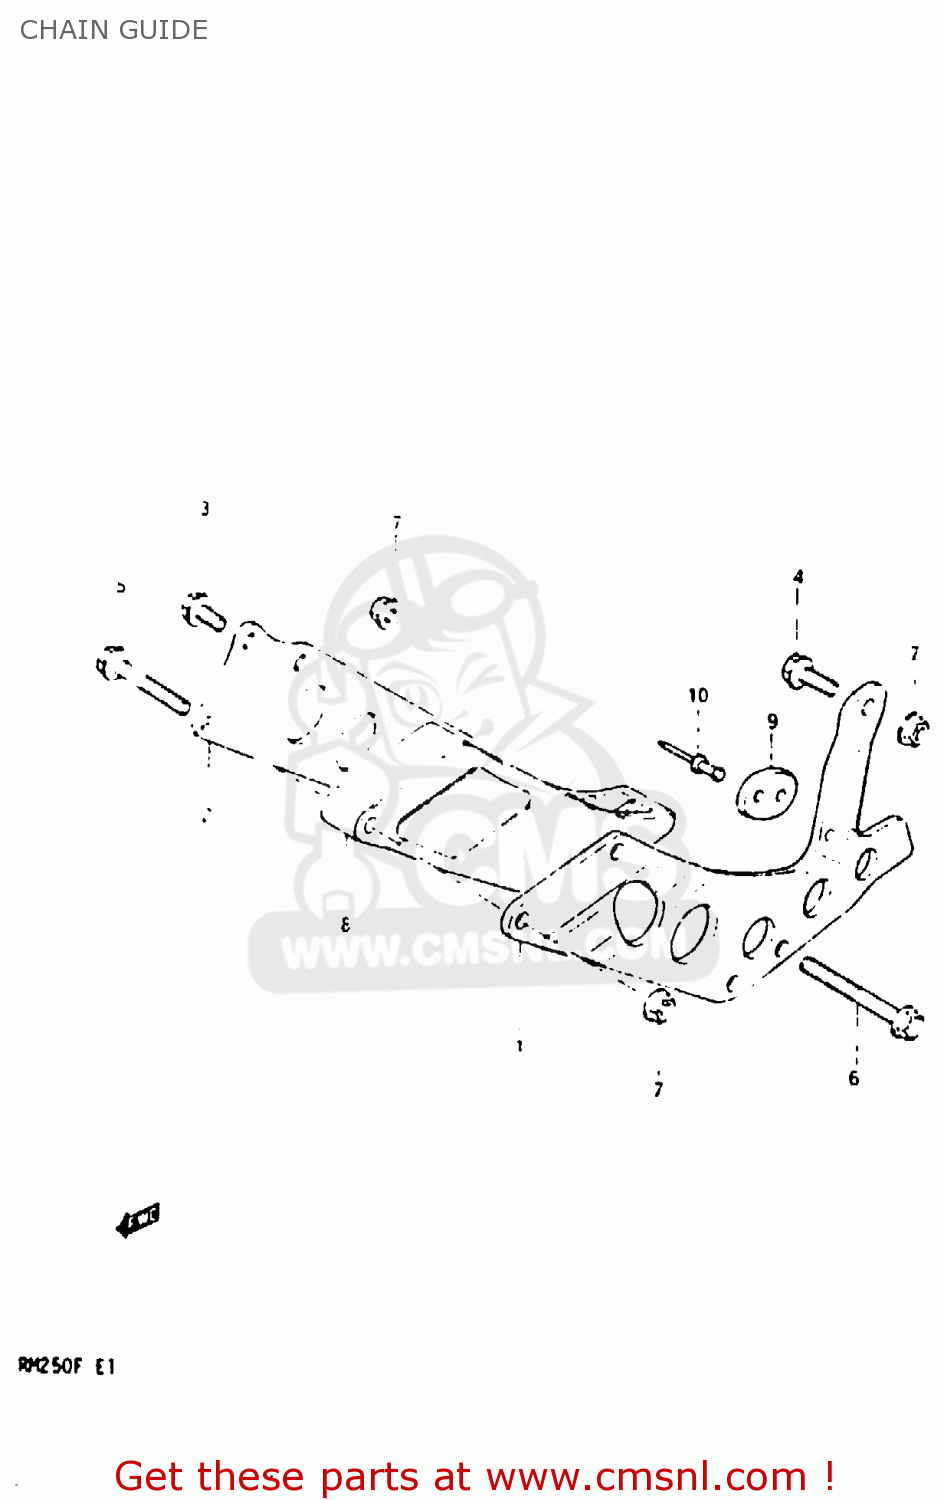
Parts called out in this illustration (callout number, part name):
1	PLATE,CHAIN GUIDE,OUTER
2	PLATE,CHAIN GUIDE,INNER
3	BOLT
4	BOLT,REAR
5	BOLT
6	BOLT,UNDER
7	NUT
8	DEFENSE,CHAIN GUIDE
9	PAD,GUIDE
10	RIVET
